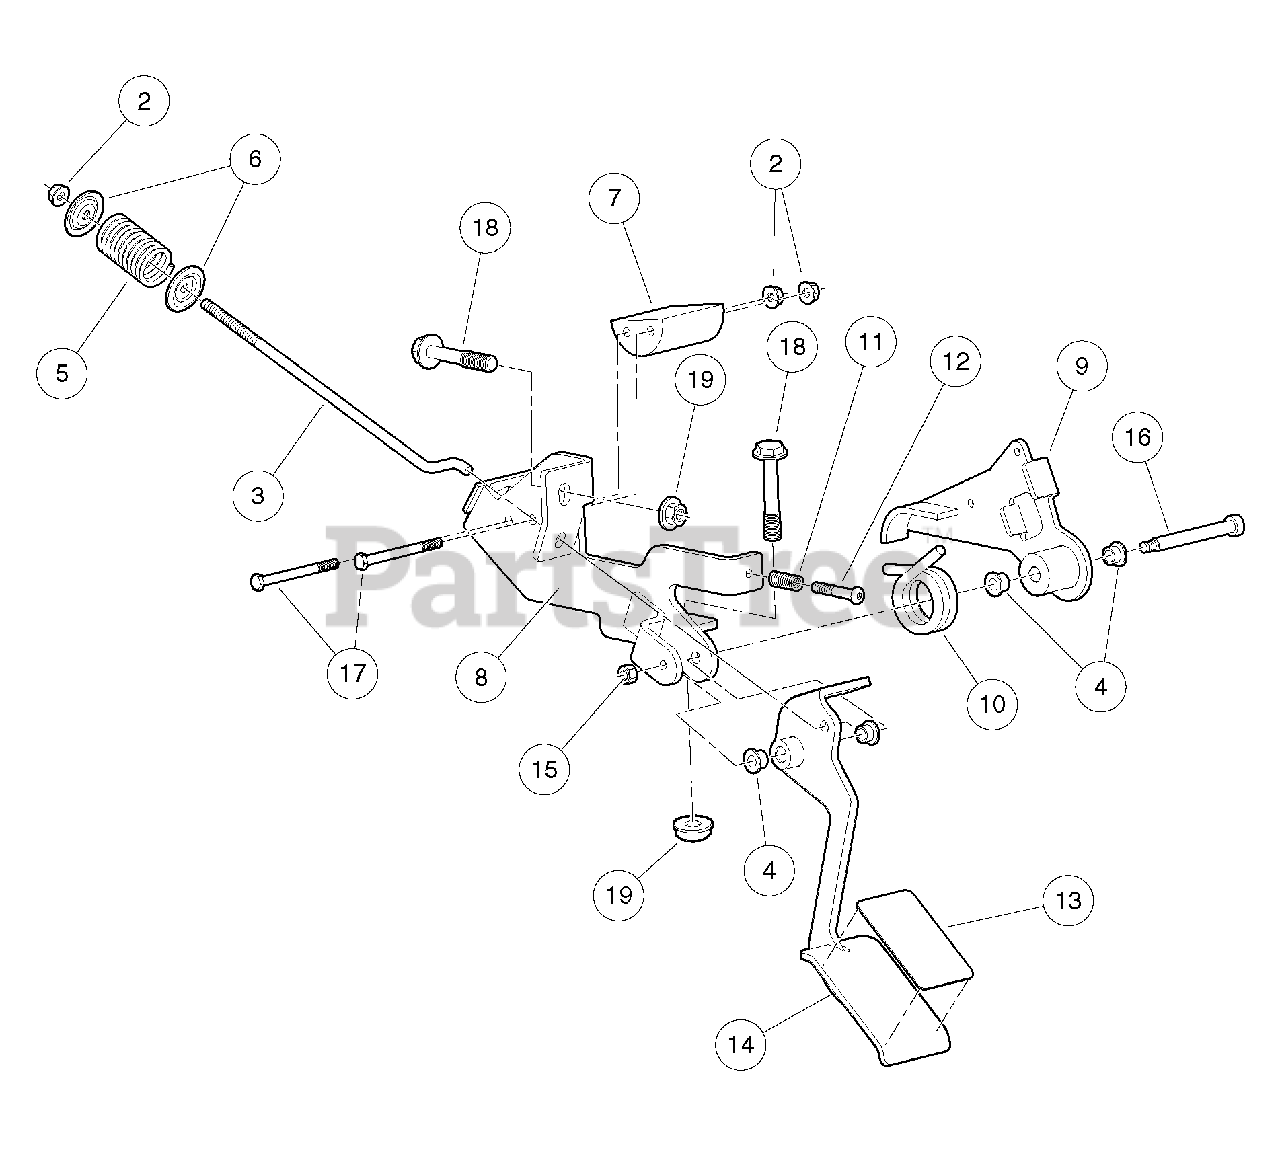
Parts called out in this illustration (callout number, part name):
1	Asm, Pedal, Accelerator
2	Nut-m6x1.0 Flng All Mtl Lock
3	Pullrod, Spring, Compression
4	Bushing, Greaseless
5	Spring, Comp, Pedal, Pullrod
6	Washer, Retaining Spring, 7mm
7	Guide, Cable, Accelerator
8	Weldment, Bracket, Pedal
9	Weldment, Lever, Motion, Lost
10	Spring, Torsion
11	Spring, Stop, Pedal
12	Bolt, Stop, Pedal
13	Pad, Grip Tape, Accelerator
14	Weldment, Pedal, Accelerator
15	Nut M6x1 Mech Def Center
16	Bolt, Shoulder, M8 X 70, Hc
17	Bolt, M6 X 1 X 70
18	Bolt Flanged Head, M8 X 1.25 X 65
19	Lock Nut, Flg M8 X 1.25 Nylon
